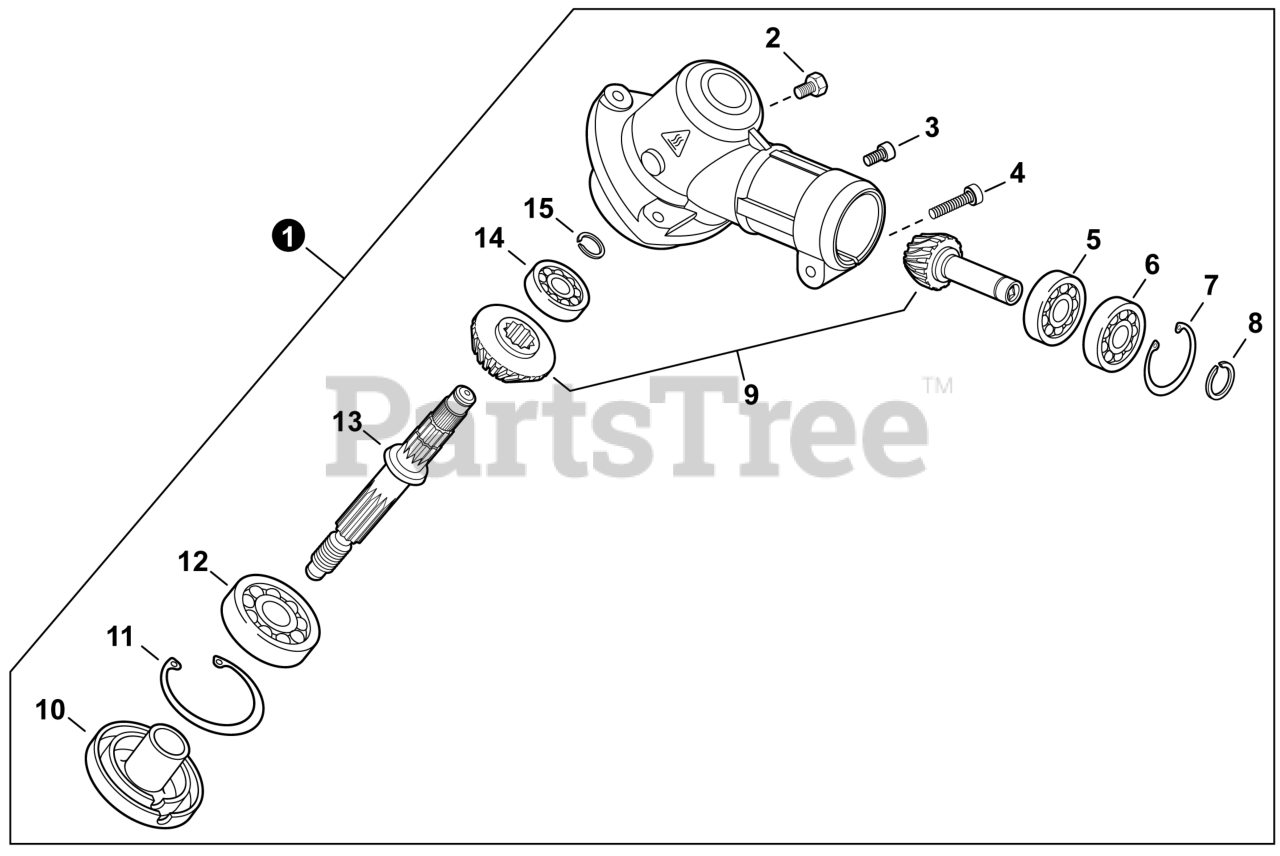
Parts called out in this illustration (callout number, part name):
1	GEAR CASE ASSY
2	BOLT M8×8
3	BOLT, TORX 5×12
4	BOLT, TORX 5×25
5	BEARING, BALL 609
6	BEARING, BALL 609
7	RING, SNAP Ø25
8	RING, SNAP Ø9
9	GEAR SET, BEVEL
10	PLATE, ADAPTOR - UPPER
11	RING, SNAP Ø42
12	BEARING, BALL 6302
13	SHAFT, GEAR
14	BEARING, BALL 629
15	RING, SNAP Ø12
